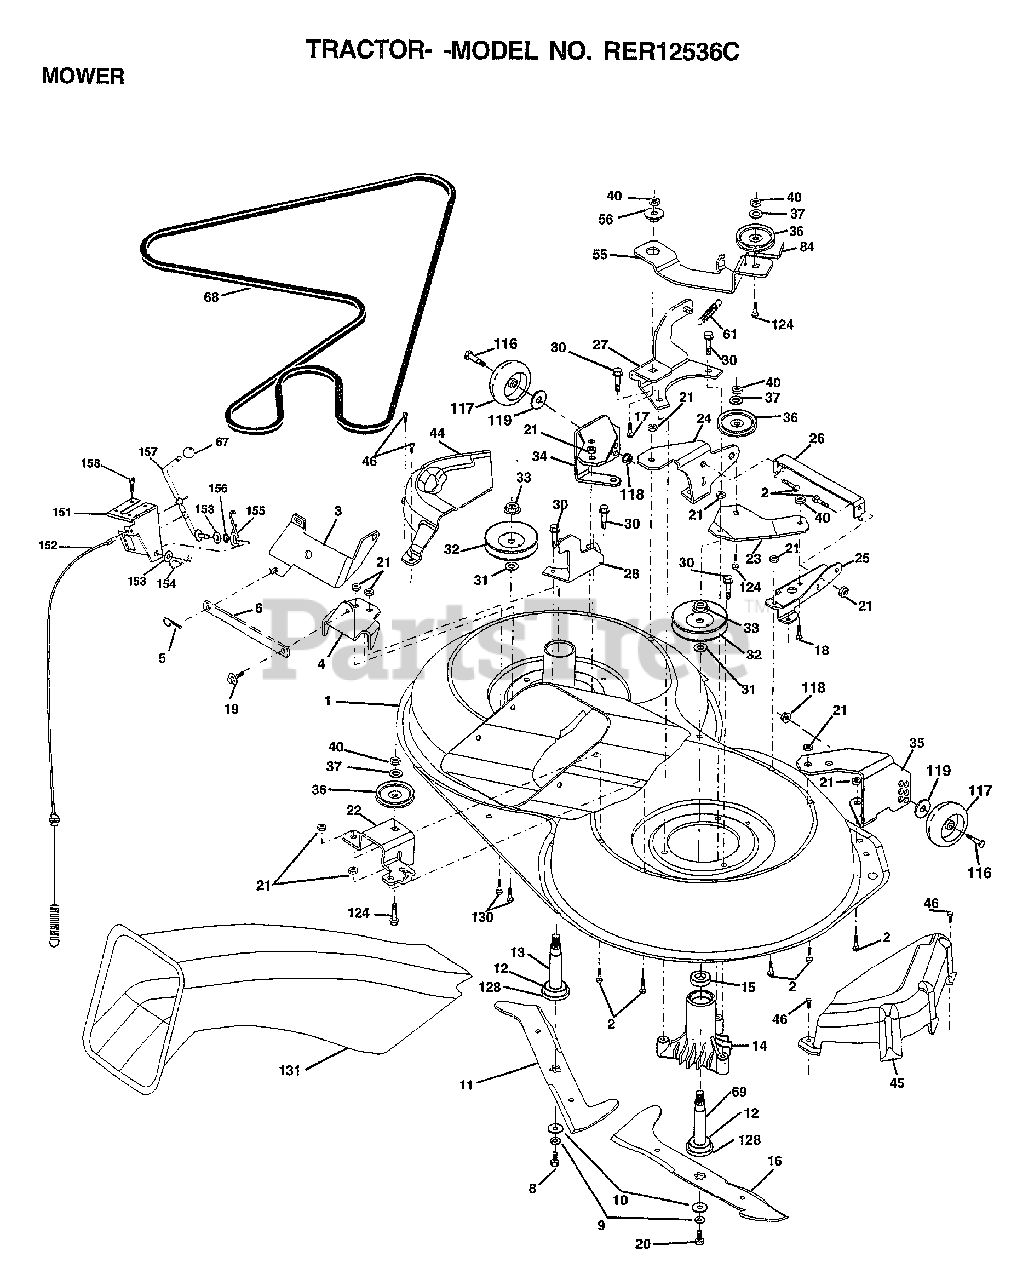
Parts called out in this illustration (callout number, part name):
1	HOUSING.ASM.MOWER
2	BOLT
3	BRKT.ASM.S-BAR.CHASSIS
4	BRKT.BAR.SWAY.DECK
6	BAR.SWAY.92.CRD
8	BLADE BOLT
10	WASHER.HARD.BLADE
11	BLADE.3-1.LH.92.CRD
12	BEARING.BALL
14	HSG ASM MANDREL
15	BEARING
16	BLADE.3-1.RH.CRD.92
17	BOLT.3/8-14X1.25
18	BOLT D
19	BOLT SHD 5/16-18
20	BOLT.3/8-24X1.25
22	BRKT.IDLER.SPRT.CRD
23	"BRKT.IDLER.SPRT.RF.92,CRD"
24	BRKT.SUSP.LF.92.CRD
25	BRKT.SUSP.RF.92.CRD
26	BRACE.SUPT.SUSP.FRT.CRD
27	BRKT.ASM.SUSP.RR.92.CRD
28	BRKT.ASM.SUSP.LR.92.CRD
30	"SCREW-THD ROLL,WA"
31	WASHER
32	PULLEY.MAND.36/46
34	BRKT.GUAGE.WHL.LF.92.CRD
35	BRKT.GUAGE.WHL.RF.92.CRD
36	PULLEY.IDLER.4.25
37	WASHER
44	COVER.MANDREL.LH.92.CRD
45	COVER.MANDREL.RH.92.CRD
46	SCREW.1/4-20X5/8
55	ARM.IDLER.92.CRD
56	SPACER.RETAINER.MOWER
61	SPRING.TENSION.BELT
67	KNOB T(3/8 HOLE)
68	HEX-BELT.92.MWR.105AA
69	SHAFT.ASM.W/LWR.BRG.RH.THD
84	"KEEPER-BELT,IDLER"
116	BOLT SHOULDER
117	WHEEL GAGE DONUT
118	LOCKNUT
119	WASHER
124	BOLT.3/8-16X1.50
128	WASHER.FELT.
131	CHUTE.BAGGER.CRD
150	BRKT CLUTCH CABLE
152	CABLE CLUTCH CRD SERVICE
153	WASHER FLAT
154	SPRING RETAINER
155	SPRING RETENTION LVR CLUTCH CAB
156	SPACER
157	ROD.CLUTCH.CABLE.3/8
158	SCREW LT
